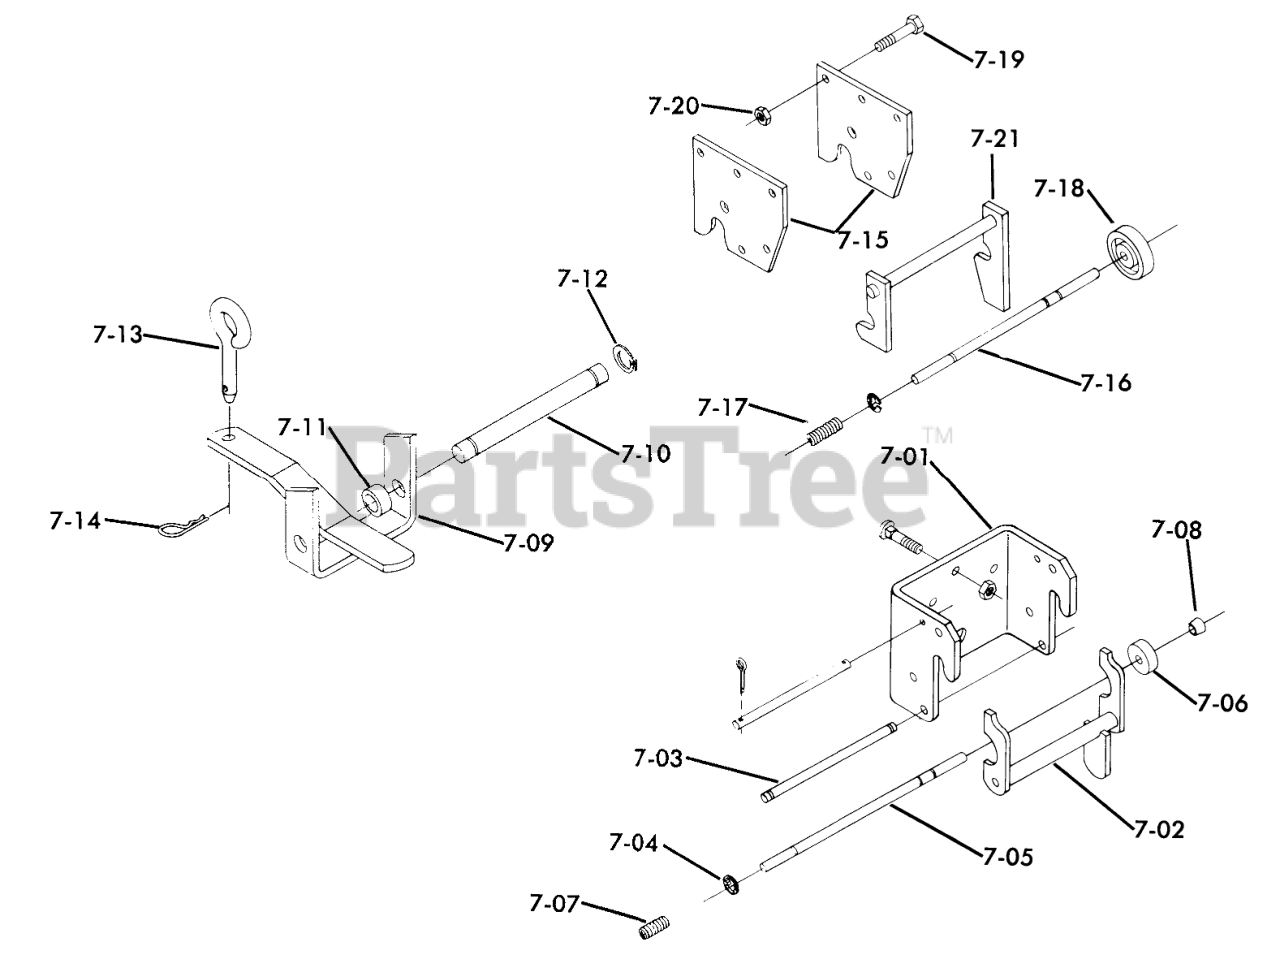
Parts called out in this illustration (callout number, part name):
7-01	Front Hitch
7-02	Assy-Latch
7-03	ROD-LATCH PIVOT
7-04	Lock Rod
7-05	ROD-LOCK
7-07	SPRING
7-08	CAP-ROD, PLUNGER
7-09	Hitch
7-10	PIN-STATIONARY HITCH
7-11	Spacer
7-12	E-RING
7-13	Pin-Tool
7-14	Hairpin Cotter
7-15	Hitch Plate
7-17	ASSY MID HITCH LA R
7-19	BOLT
7-20	Nut
7-21	ASSY MID HITCH LA R
